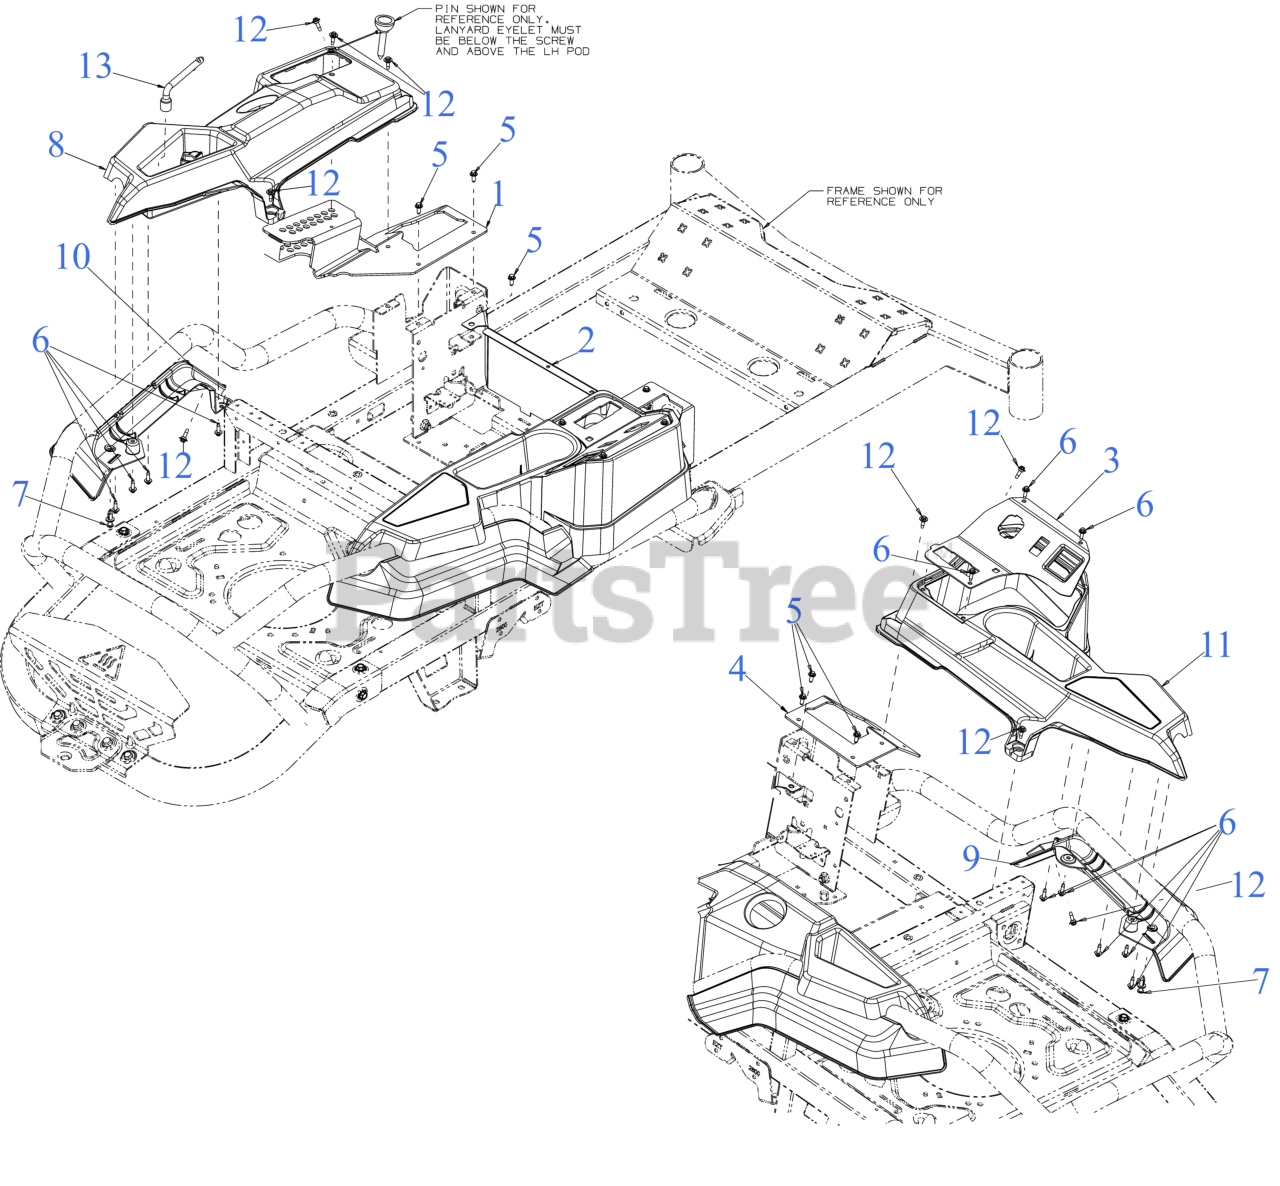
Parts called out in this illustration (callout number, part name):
1	HEIGHT INDEX BRACKET (LH)
2	SEAT BOX FRONT PLATE
3	CONSOLE COVER (RH)
4	CONTROL BRACKET (RH)
5	SCREW M6-1 x .625
6	SCREW 1/4-10 x .750
7	PLASTIC RIVET
8	CONSOLE (LH)
9	FENDER CONSOLE (RH)
10	FENDER CONSOLE (LH)
11	CONSOLE (RH)
12	SHOULDER SCREW M6-1 .368 X.115
13	MULTI TOOL 1/2" SOCKET
